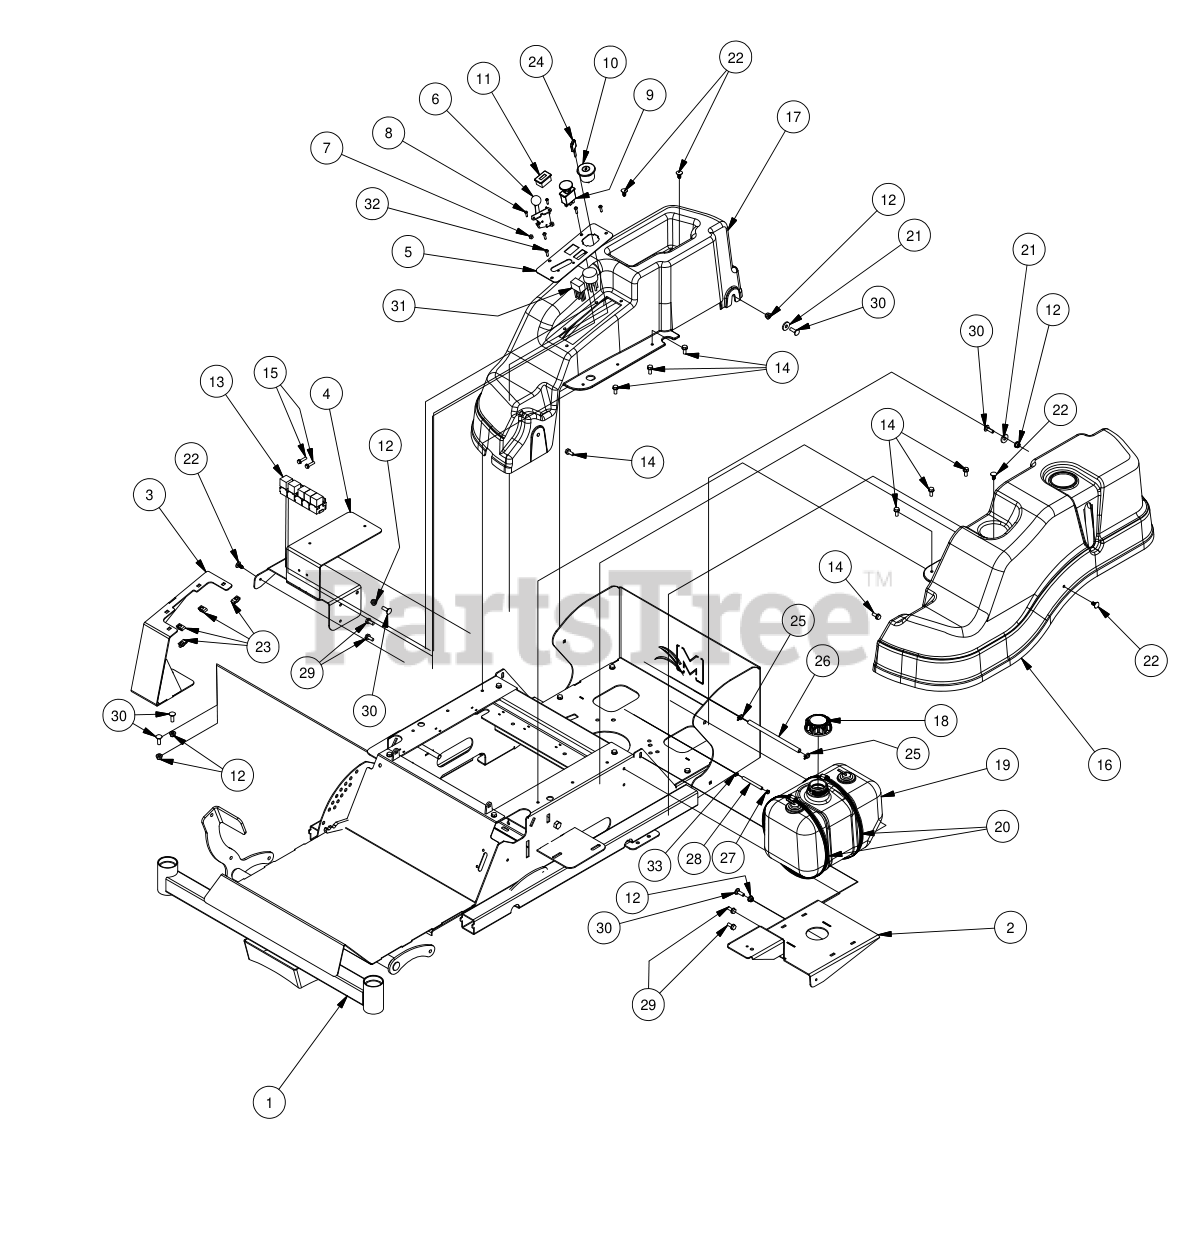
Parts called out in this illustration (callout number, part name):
1	2014 54" MZ Magnum Frame
2	MZ Magnum Gas Tank Bracket Assy
3	MZ Magnum Shroud Control Support Assy
4	MZ Magnum Shroud Storage Support Assy
5	Control Panel New MZ
6	Throttle Lever
7	10-24 Nylon Insert Locknut
8	10-24 X 5/8 BS Button Head Bolt
9	PTO Engager
10	Ignition Switch
11	Tachometer
12	5/16" Nylon Flange Nut
13	Relay Terminal
14	5/16 x 3/4 washer head type F screw
15	1/4 x 1 Hex Head Tek screw
16	2013 Magnum Left Fender Shroud
17	2013 Magnum Right Fender Shroud
18	Fuel Cap 2013 Magnum-080165AE
19	2.5 Gal EPA Tank Assy-071145AE
20	MZ Magnum Tank Clamp-63164
21	.360 ID Plastic Washer
22	Ratchet Fastener
23	10-24 "U" Nut
24	Ignition Key
25	1/4 Fuel Hose Clamp
26	1/4" Fuel Line Hose
27	1/4" Hose Clamp
28	3/16" Clear Vinyl Tubing
29	5/16 x 3/4 washer head type F screw
30	5/16" x 1" Carriage Bolt
31	wiring harness
32	10-24 x 1 BS C/S 18-8 SS
33	3/16" Vinyl Hose Clamp
